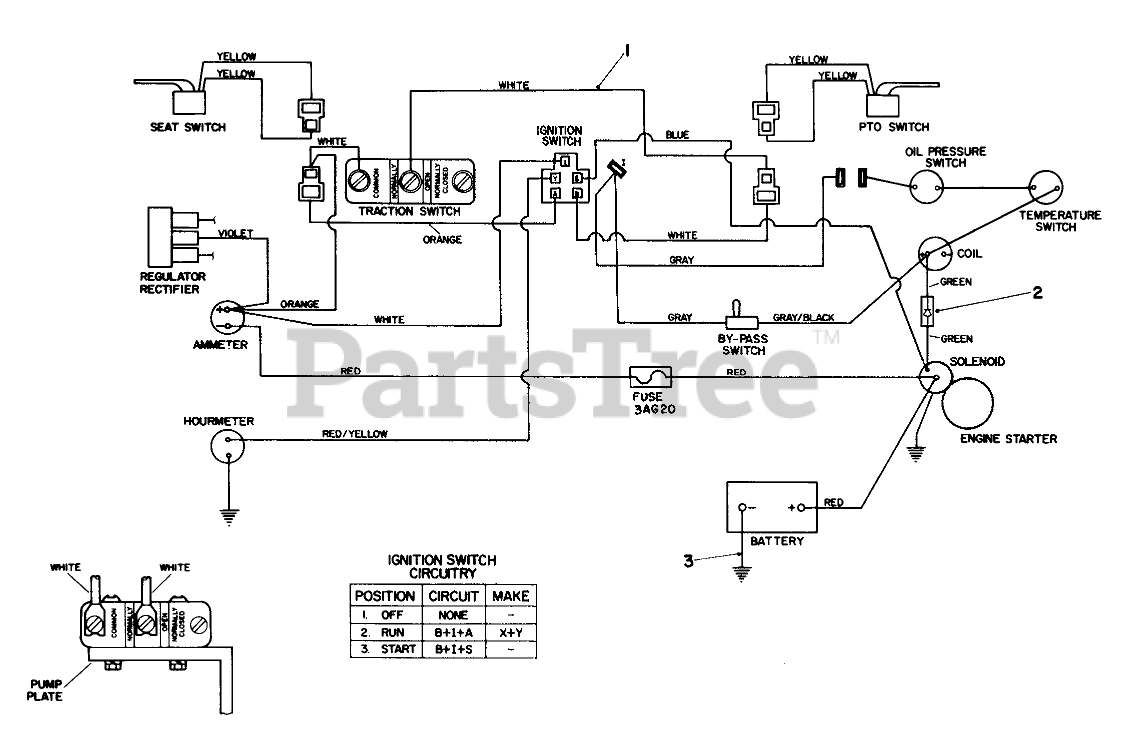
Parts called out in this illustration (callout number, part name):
1	Wire Harness (Incl. Ref. #2)
2	JUMPER WIRE
3	BATTERY GROUND WIRE
